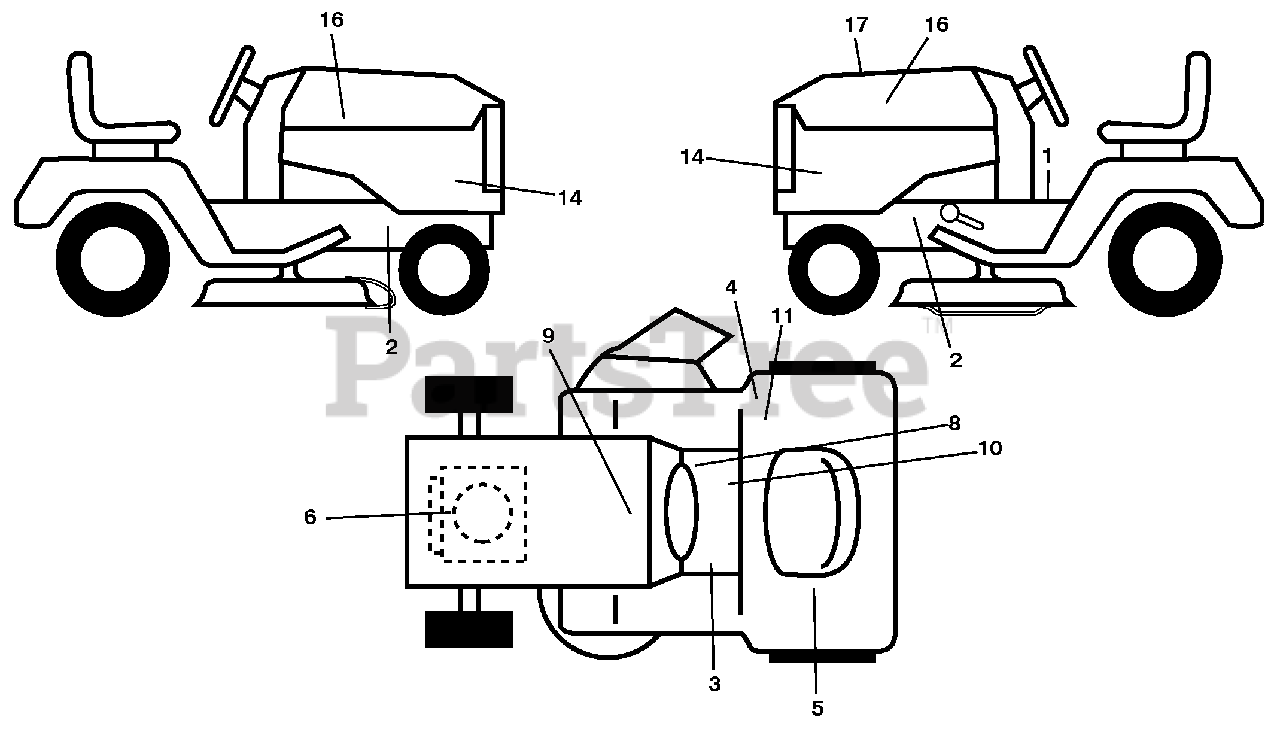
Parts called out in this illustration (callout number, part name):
1	Decal, Operator's
2	Decal, Hot Muffler
3	Decal, Brake Clutch
4	Decal, 80 DBA
5	Decal, Warning Reserve
6	Decal, Eng. H.P.
7	Decal, Warning Eng. Sym.
8	Decal, Brake Parking
9	Decal, Battery Dnge/Poi
10	Decal, Oper. Cruise Sym.
11	Decal, Tick Mark
14	Decal, Panel Side
16	Decal, Hood Logo
17	Decal, Replacement
